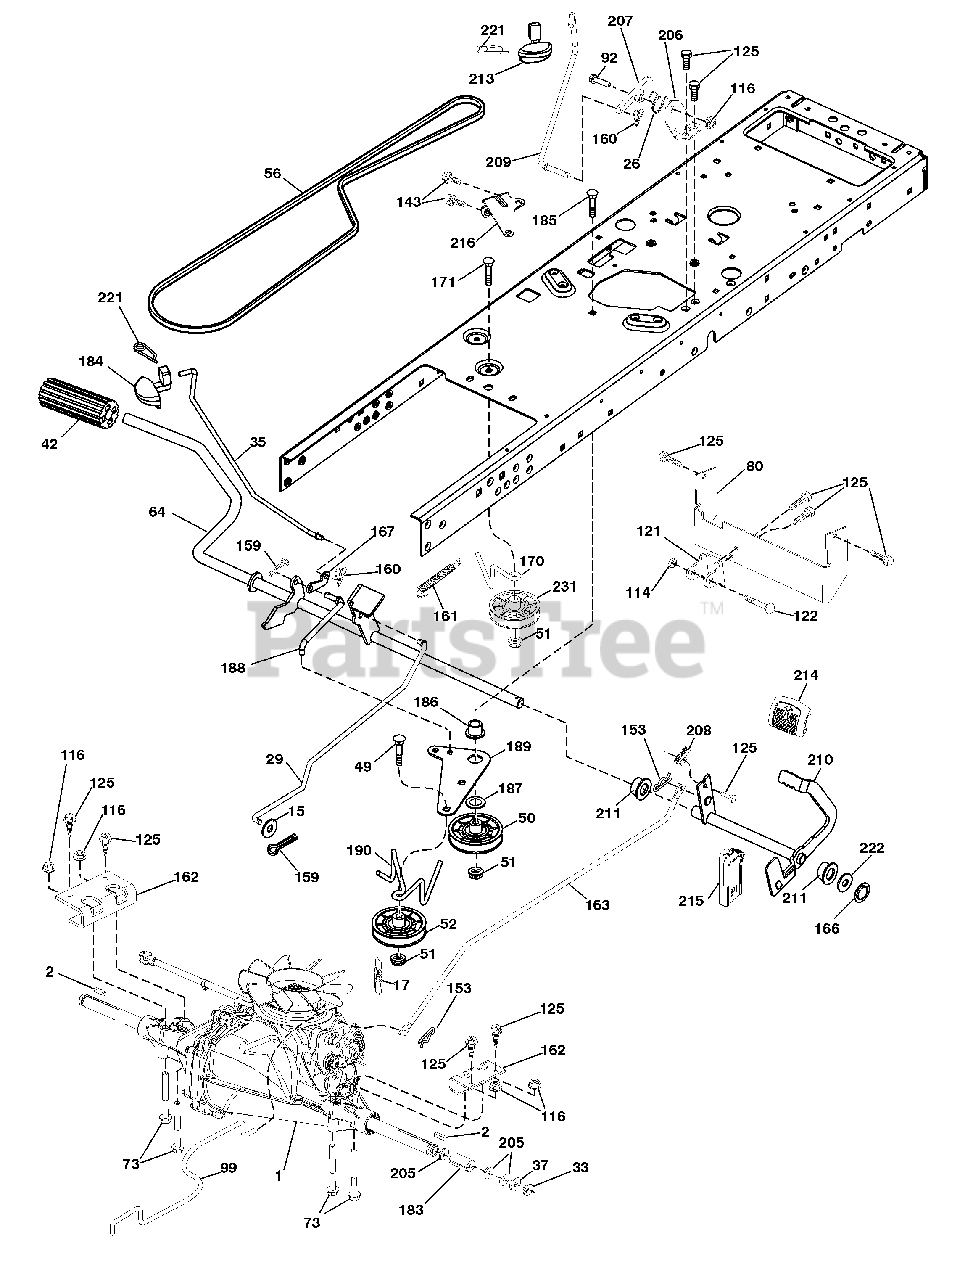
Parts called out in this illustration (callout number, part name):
1	Transaxle, Hydro Gear T2
2	Key Square
15	Washer 13/32 x 13/16 x 16 Ga.
17	Spring, Brake
26	Spring Return Cruise
29	Rod, Brake
35	Rod, Brake, Park
37	Washer 25/32 x 1-1/4 x 16 Ga.
42	Cover, Foot Pedal
50	Pulley Idler Flat
51	Lock Nut 3/8-16
52	Idler V-Groove 910" Offset
56	V-Belt, Drive
64	Shaft Asm. Pedal Brake Control
73	Bolt Hex 5/16-18 Gr. 5
80	Strap Torque
92	Bolt Fin Hex 5/16-18 unc x 1.25
99	Rod Spring Bypass
114	Nut Lock HX W/Ins 5/16-18
116	Nut Lock Hex Flange 5/16-18
121	Bracket Strap Torque
122	Bolt 5/16-18 x 2.50
125	Screw 5/16-18 x 3/4
143	Screw 5/16-18 x 1/2
153	Retainer Spring 1"
159	Pin Cotter 1/8 x 3/4
160	Retainer Clip
161	Spring, Return, Clutch
162	Adapter Transaxle
163	Rod Control
166	Nut Push
167	Latch Brake Parking
170	Keeper V-Idler
183	Spacer Axle
184	Handle Parking Brake
186	Spacer Retainer
187	Washer
188	Link Clutch Ground Drive
189	Bellcrank Ground Drive
190	Keeper Bellcrank Ground Drive
205	Washer 25/32 x 1-5/8 x 16 Ga.
206	Bracket Mount Latch Cruise
207	Latch Control Cruise
208	Gear Sector Control Cruise
209	Rod Control Cruise
210	Rocker Asm. Pedal Control
211	Bearing Nylon
213	Knob Control Cruise
214	Pedal Forward
215	Pedal Reverse
216	Bracket Pulley Idler
221	Retainer Spring Clip Handle
222	Washer 21/32 x 1-1/4 10 Ga.
231	Idler V-Groove 1.688" Offset
